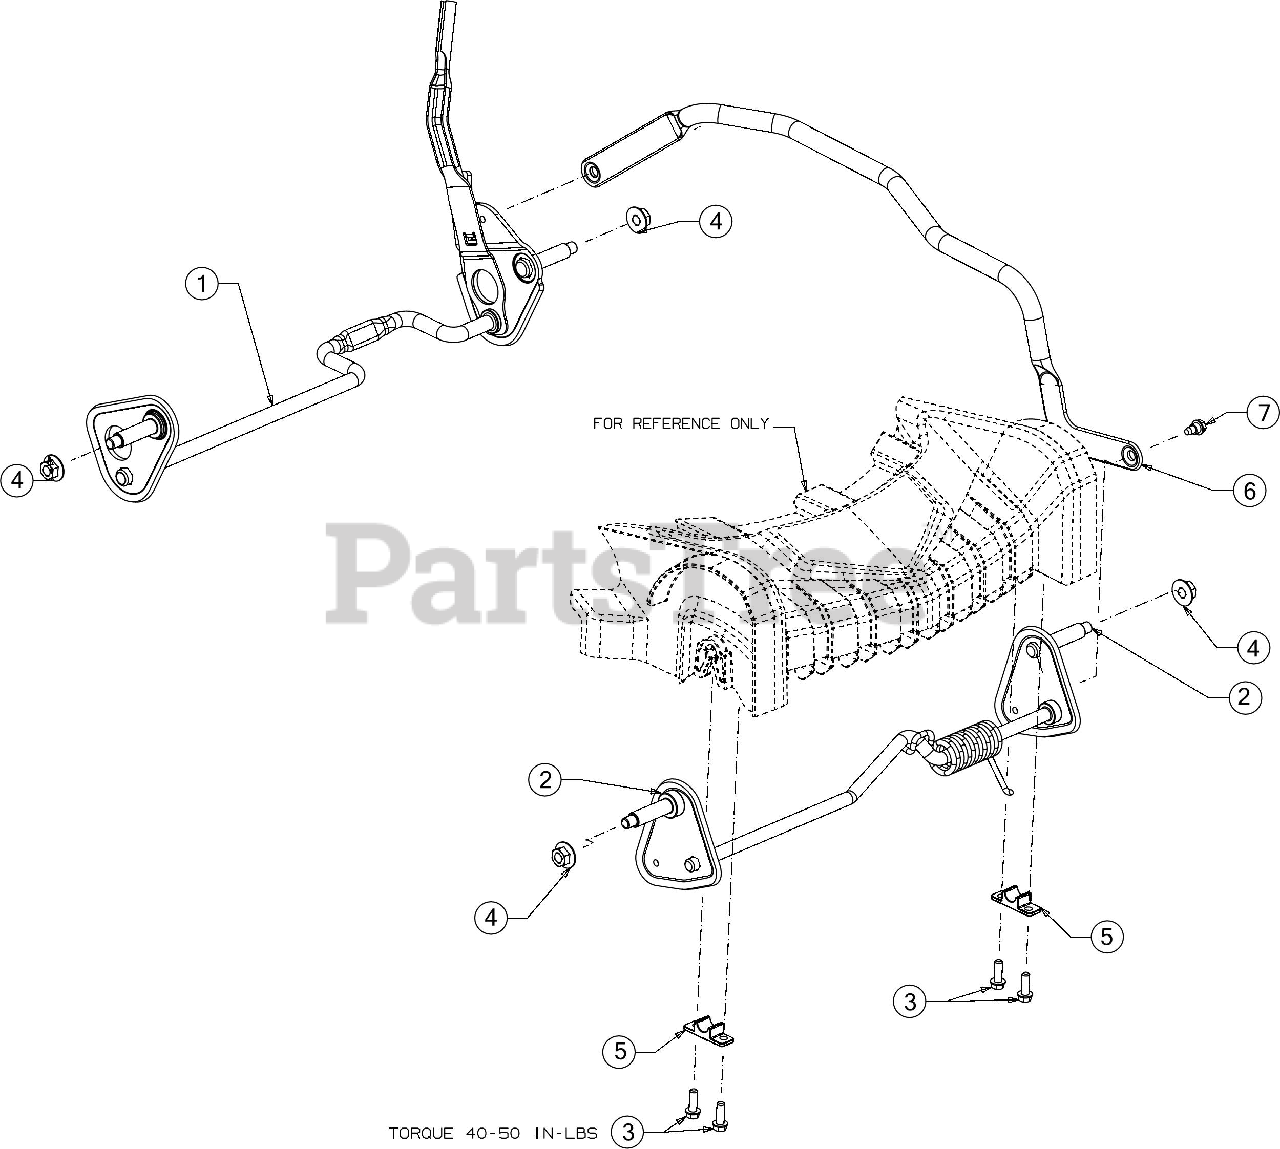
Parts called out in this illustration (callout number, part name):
1	HEIGHT AXLE ASSEMBLY
2	FRONT AXLE ASSEMBLY
3	SCREW 1/4-15 x .750
4	FLANGE LOCK NUT
5	BLOCK BUSHING
7	SHOULDER SCREW 1/4-20 x .50
